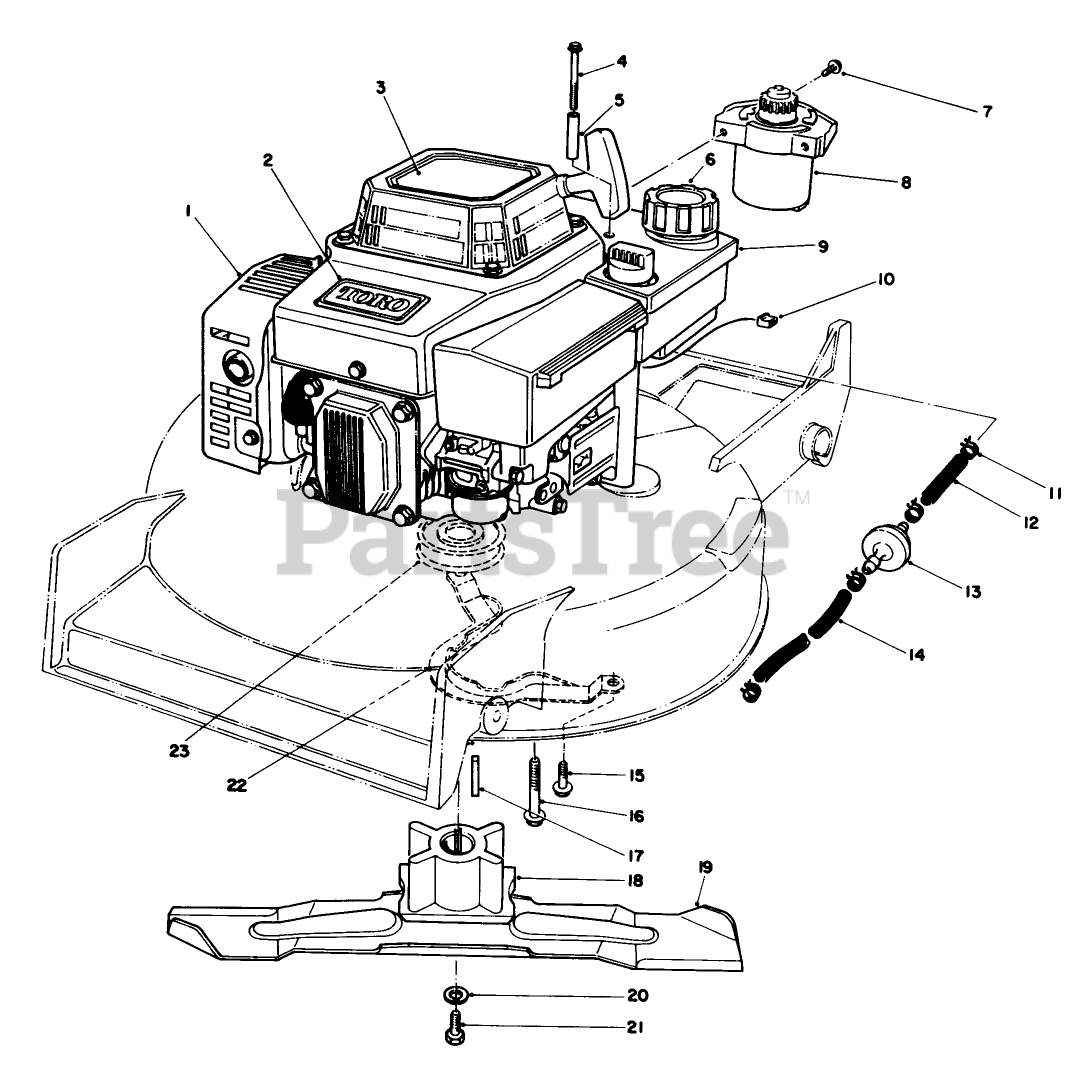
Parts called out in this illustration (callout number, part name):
1	Engine
4	THRD FORMING SCREW
5	TUBULAR SPACER
6	GAS CAP ASM
8	STARTER MOTOR ASM
9	TANK ASM
10	CONNECTOR BODY
11	CLAMP-FUEL LINE
12	HOSE-FUEL
13	FILTER-FUEL
14	HOSE-FUEL
17	KEY-SQUARE
20	WASHER-LOCK
21	SCREW-BLADE
23	PULLEY-DRIVER
